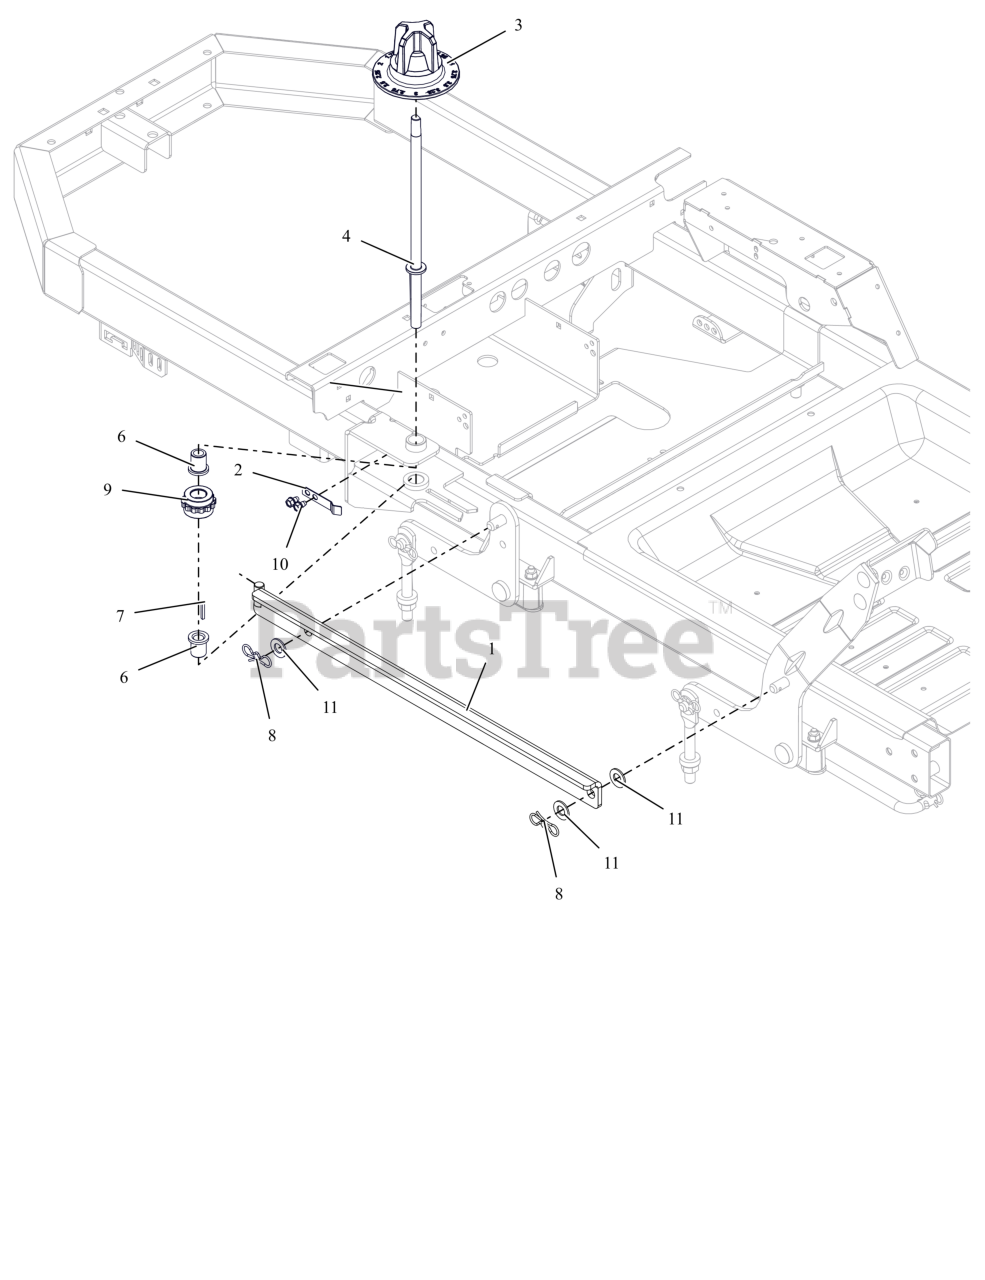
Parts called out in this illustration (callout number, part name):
1	WLDMT, HOC LINK
2	ARM, HOC DETENT
3	KNOB, HOC DIAL
4	SHAFT, CAM
6	BSHG-FLG, .503X.750X.875X1.00
7	KEY, 1/8 X 1/8 X 1.0
8	PIN, BOWTIE .091X1.875 ZCC
9	GEAR, HOC INDEX
10	SCR,TAP .25-20X.375 HWH TR ZCC
11	WSHR-FL-NYL .518X1.000X.080
